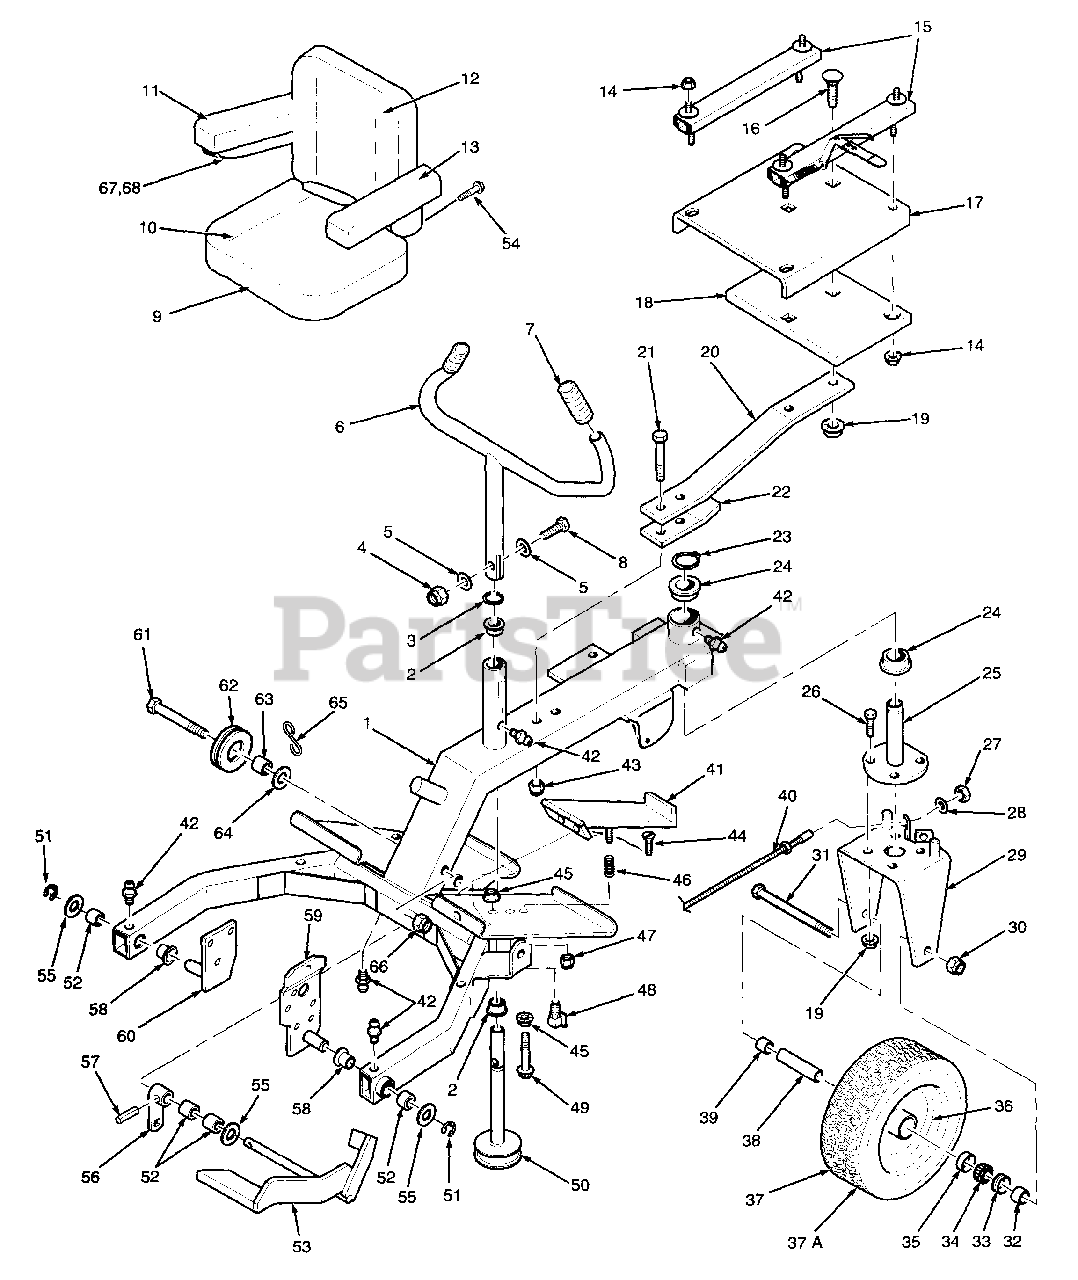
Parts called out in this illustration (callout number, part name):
1	Steering Frame
2	Bronze Bushing, 7/8 ID x 1.0 Flanged
3	Retaining Ring, 7/8 external
4	Hex Nut, Elastic Stop 5/16-18
5	Flat Washer, 5/16 (3/8 x 7/8 x 13 ga.)
6	Steering Handle
7	Grip
8	Bolt, Hex Hd., 5/16-18 x 1-3/4"
9	Seat Assy.
10	Cushion Assembly
11	Arm Pad - R.H.
12	Seat Back Cushion
13	Arm Pad - L.H.
14	Serr. Fl. HH. Nut, 5/16-18
15	Seat Adjuster Track
16	Bolt, RDHD Carr. 3/8-16 x 1-1/2 (52" & 61")
17	Seat Plate
18	Ballast, Seat Mount (72" cutter deck only)
19	Serr Fl. Hex Nut, 3/8-16
20	Seat Spring
21	Bolt, Hex Hd., 7-16-14 x 3-1/2"
22	Reinforcement, Seat Spring
23	Retaining Ring, 1-1/8" external
24	Bushing, Oilite - 1-1/8 ID x 1.0 Flanged
25	Rear Wheel Pivot
26	Bolt, Hex Hd., 3/8-16 x 1-1/4"
28	Lock Washer, 3/8 Internal Tooth
29	Rear Wheel Yoke
30	Hex Elastic Stop Nut, 5/8-11
31	Bolt, Hex Hd. 5/8-11 x 9"
32	Spacer, Rear Wheel, short
33	Seal, Grease
34	Bearing Cone
35	Bearing Cup
36	Rim Only
37	Rear Wheel Assy.
37A	Tire Only
38	Sleeve, Rear Wheel
39	Spacer, Rear Wheel
40	Cable, Steering
41	Pedal, Foot Safety Switch
42	Grease Fitting
43	Hex Elastic Stop Nut, 7/16-14
44	Screw, Phillips flat hd #10-32 x 3/4"
45	Serr. Fl. Hex Nut, 1/4-20
46	Spring, Foot Safety Switch
47	Hex Nut, Elastic Stop Lock, 1/4-20
48	Switch, Foot Safety
49	Bolt, Hex Hd., 1/4-20 x 1-3/4"
50	Steering Shaft
51	Retaining Ring 3/4 Ext. "E"
52	Bushing, oillube - 3/4 ID x 1.0
53	Foot Pedal
54	Screw w/washer, 1/4-20 x .75"
55	Flat Washer, 3/4 x 1-1/4 x 16 Ga.
56	Foot Pedal Arm
57	Pin, Drive Lock 3/16 x 1-1/4"
58	Bushing, oillube - 3/4 x .50 Flanged
59	Sulky Mtg. Brkt. L.H.
60	Sulky Mtg. Brkt. R.H.
61	Bolt, Hex Hd., 1/2-13 x 5-1/2"
62	Pulley, Winch Cable
63	Bushing, oillube - 1/2 ID x .56
64	Flat Washer, 1/2 (.562 x 1.375 x .109)
65	Retainer, Winch Cable
66	Hex Elastic Stop Nut, 1/2-13
67	Arm Rest Bracket, Left Hand
68	Arm Rest Bracket, Right Hand
